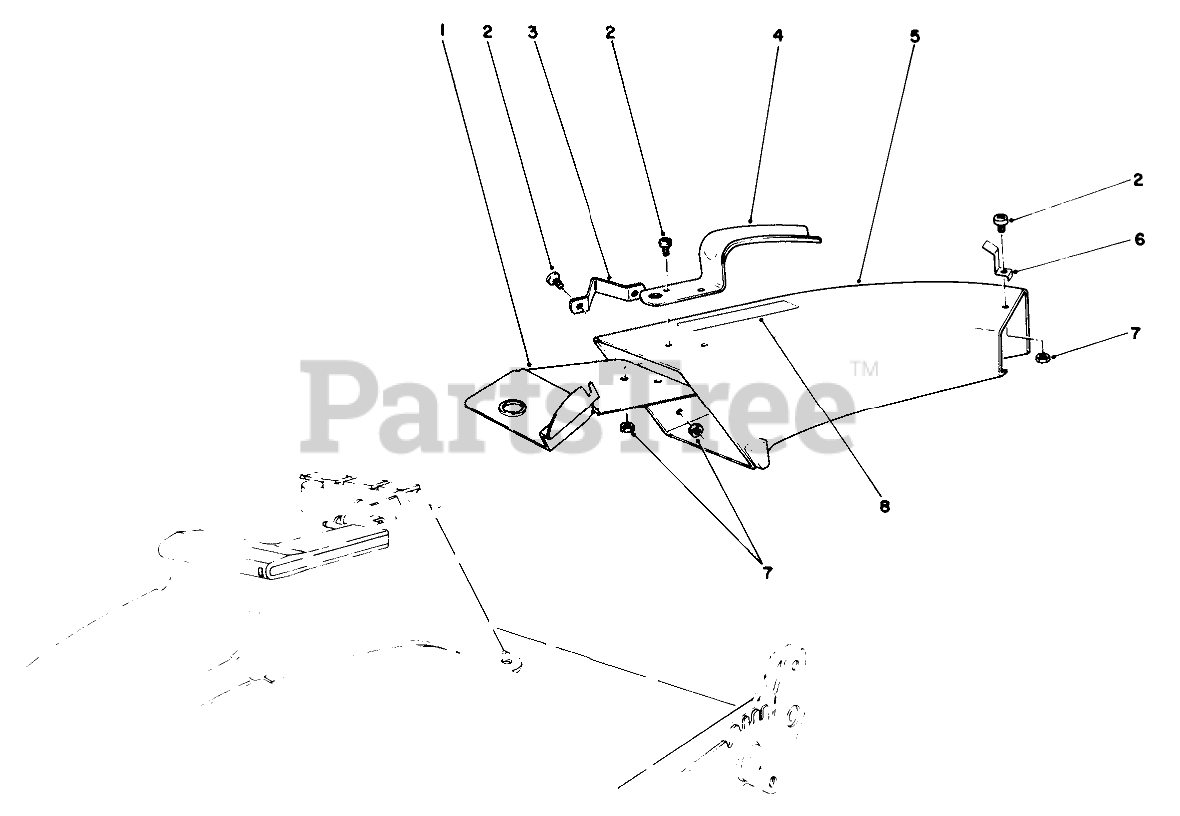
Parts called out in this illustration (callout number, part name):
1	Plate-Discharge Chut
2	10-24 X 5/8 PAN HD MS
3	SIDE BRACKET
4	CHUTE HANDLE
5	Chute-Discharge
7	NUT-LOCK, NI
8	DECAL CAUTION
